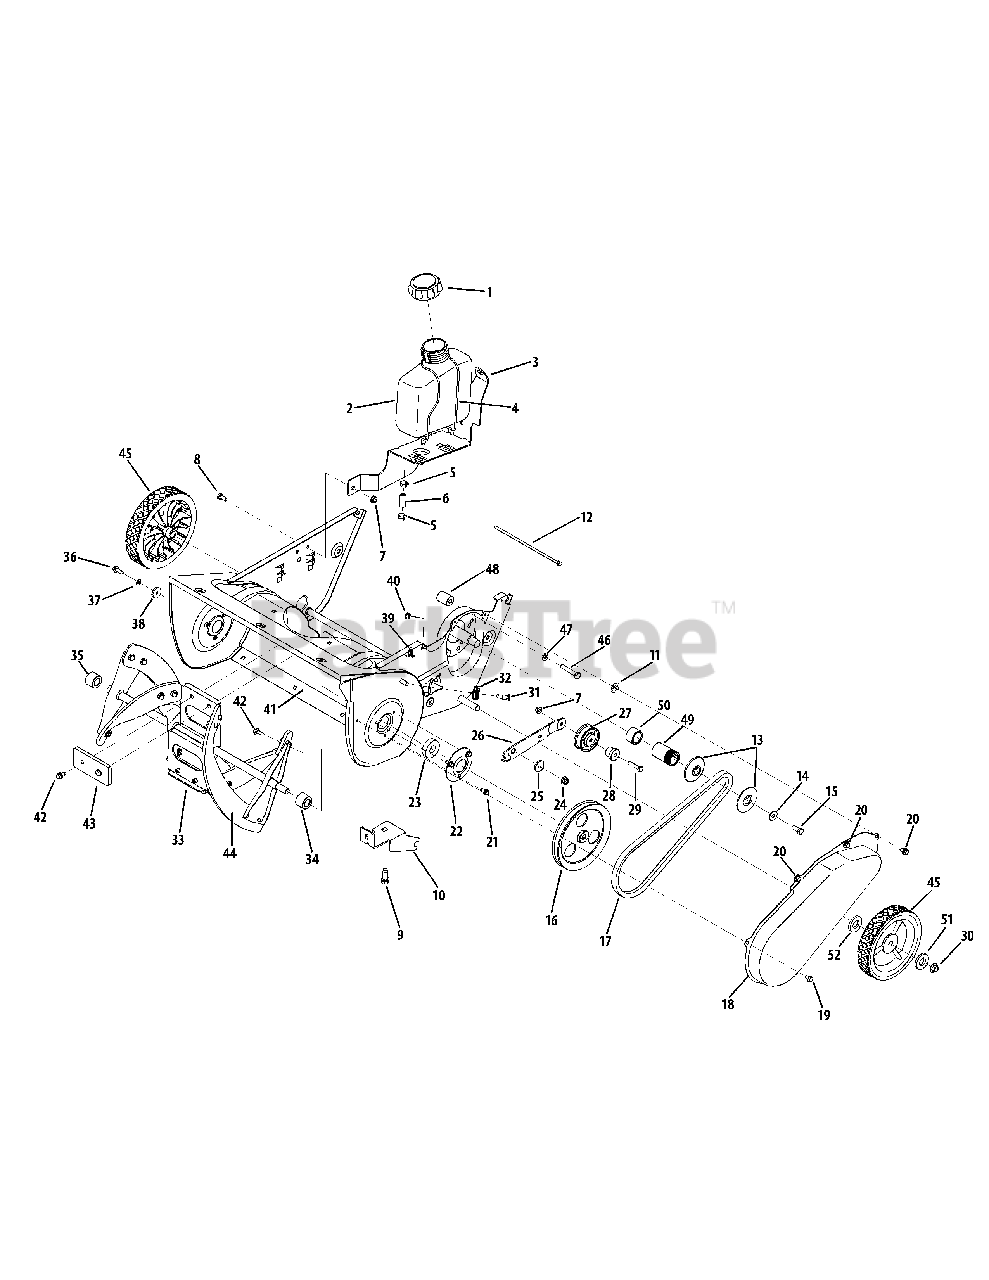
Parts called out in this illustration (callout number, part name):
1	Fuel Cap
2	Fuel Tank, 2 Qt.
5	Hose Clamp, .490
6	Fuel Line Hose
7	Flange Lock Nut, 1/4-20
8	Hex Bolt, 1/4-20 x .620
9	Screw, 3/8-16 x .75
12	Cable Tie, 7.5"
13	Pulley Half, .625 ID x .225 OD
13	Pulley Half, 4L-V x 2.30
14	Bell Washer, .343 x .880 x .062
14	Flat Washer, .406 x 1.25 x .157
15	Hex Bolt, 5/16-24 x .750
15	Hex Screw, 3/8-24 x 1.50
16	Pulley, 1/2 x 6.00
17	V-Belt
19	Hex Screw, 1/4-20 x .375
20	Hex Screw, 1/4-14 x .625
21	Hex Screw, 1/4-14 x .500
23	Ball Bearing, .625 x 37 x 12
24	Flange Lock Nut, 5/16-18
25	Shoulder Spacer
27	Idler Pulley Assembly, 1.917
28	Shoulder Spacer, .280 x .785 x .538
29	Hex Screw, 1/4-20 x 1.25
30	Push Cap, 1/2
31	Shoulder Screw,
32	Cable Roller
33	Auger Assembly, 21"
34	LH Spacer
35	RH Spacer
36	Hex Screw, 1/4-20 x .750
37	Lock Washer, 1/4
38	Flat Washer, .265 x .938 x .120
39	Extension Spring, .33 x 1.12
40	Hex Lock Nut, 1/4-28
41	Auger Housing Assembly, 21" Red
41	Auger Housing Assembly, 21" Green
41	Auger Housing Assembly, 21" Grey
42	Hex Screw, 1/4-14 x .75
43	Rubber Pad
44	Spiral Crescent
45	Wheel, 7 x 1.5 (Gray)
45	Wheel, 8 x 1.7 (Gray)
46	Hex Bolt, 5/16-24 x 1.75
47	Lock Washer, 5/16
48	Spacer, .875 x .320 x1.027
49	Spacer, .875 x 1.185
50	Spacer, .88 x 1.18 x .74
51	Flat Washer, .53 x .93 x .050
52	Flat Washer, .510 x 1.000 x .125
